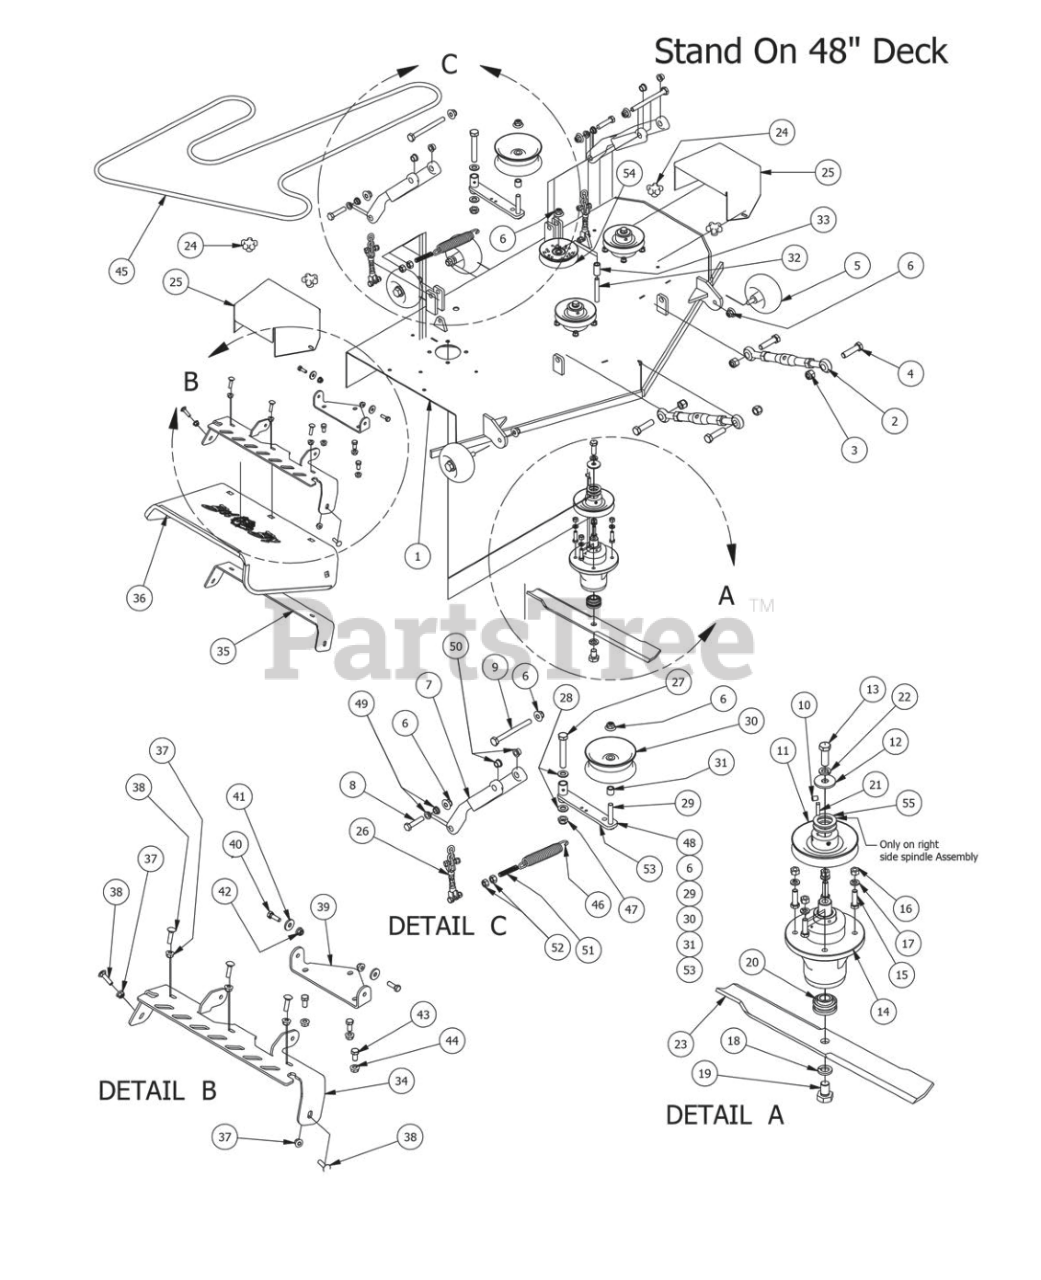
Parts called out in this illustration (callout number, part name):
2	Turnbuckle (Top Link)
3	5/8 Std NC Nylock Nut
4	5/8" x 2 1/2" Hex Bolt
5	Deck Wheel
6	1/2-13 Nylon Flange Nut-Orange
7	Deck Arm Assembly
8	1/2-13X 2-1/4 GR Hex Bolts
9	1/2" x 5 1/2" Bolt
10	5/16 Set Screw
11	5" Deck Pulley
12	1/2 Belleville Washer
13	1/2"-20 x 1 1/2 - Grade 5 Fine Thread Bolt
14	Double Bearing Spindle
15	3/8" x 1 1/4" Hex Bolt
16	3/8-16 Hex Nuts Zinc
17	3/8" Lock Washer
18	5/8" Lock Washer
19	5/8" x 1 1/2" Grade 8 Bolt
20	Double Bearing For Spindle
21	1/4" x 1" Key
22	1/2" Lock Washer
23	Fusion Blade
24	5/16" Knob
25	Pulley Cover
26	4- Link Adjustable Deck Hange
27	5/8" x 4" Hex Bolt
28	.635 ID Plastic Washer
29	1/2-13 x GR 5 Hex Bolt Zinc
30	5 3/4" Deck Idler Pulley
31	3/4 OD x 1/2 ID x 3\4 Length
32	1/2 x 3 1/2 Flange Bolt Grade 8
33	.502 ID X.75 OD X 1.500 Leng
34	Upper Hanger
35	Discharge Lower Chute Bracket
36	Rubber Discharge Chute
37	5/16" Nylon Flange Nut
38	5/16" x 1 1/4" Carriage Bolt
39	Discharge Chute Hanger (deck mounted)
40	5/16" x 1" Bolt
41	.360 ID Plastic Washer
42	5/16" Nylon Flange Nut
43	3/8" x 3/4" Hex Bolt
44	3/8" Flange Nut
45	B111 Belt 48" Stand On
46	2009 Deck/Pump Idler Spring
47	5/8" Nylock (1/2 Jam)
48	Deck Idler Assembly Components 6,29,30,31,53
49	Flange for lower Deck Arm
50	Flange Bushing For Deck Arm Upper
51	All Thread-pump Idler Tensioner
52	1/2" Hex Nut
53	Deck Idler 2009 AOS
54	4-3/4 Idler Pulley
55	1 1/8" Flat Spacer
